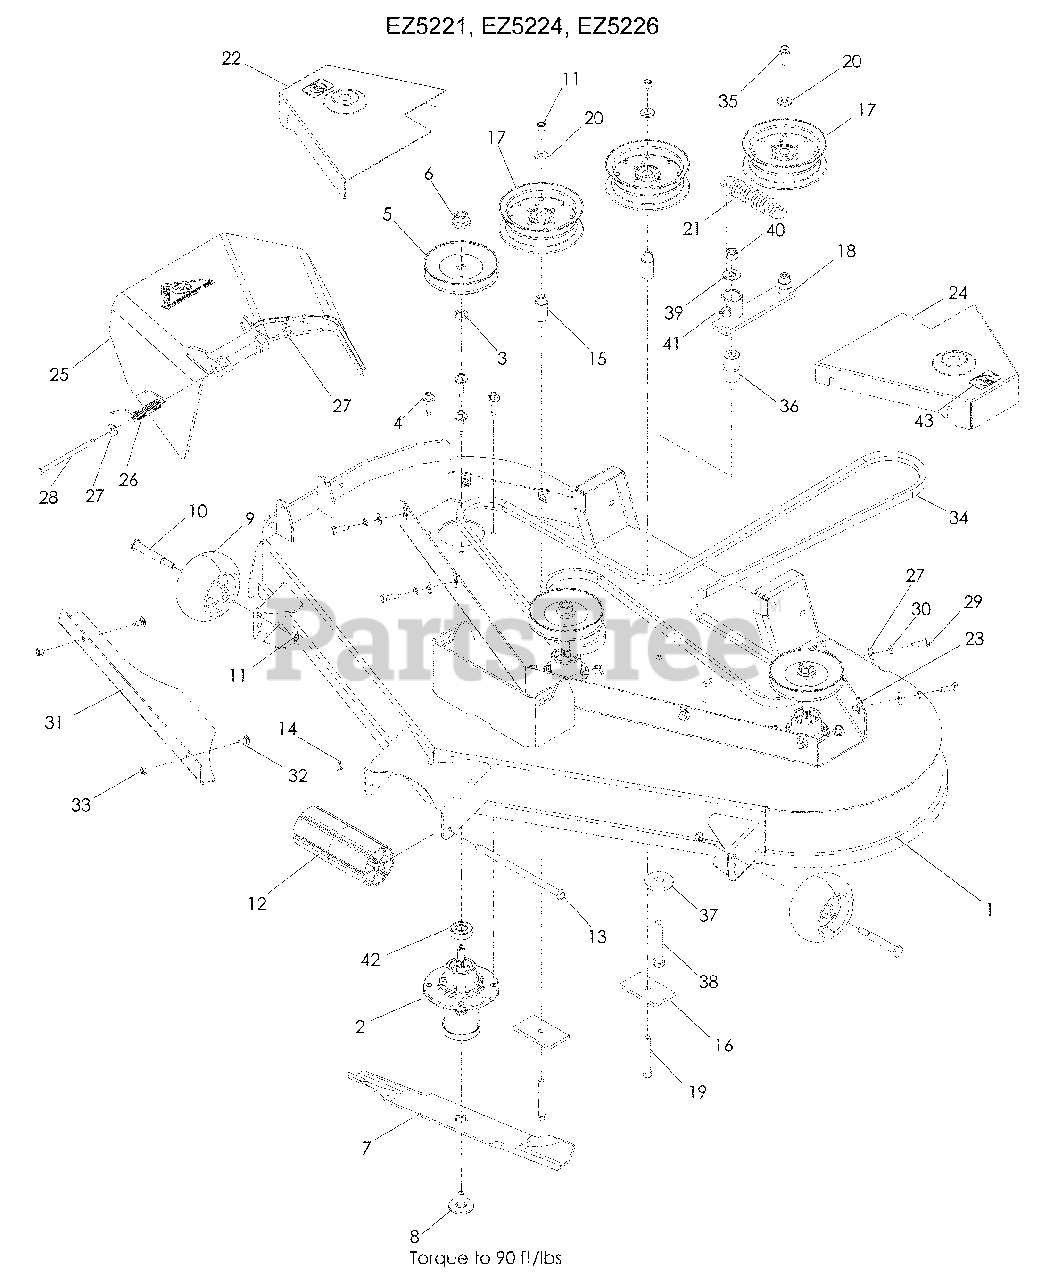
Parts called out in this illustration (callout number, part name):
1	DECK w/DECALS
2	HOUSING ASSM
3	WASHER, SPACER
4	SCREW 5/16 -18 x WSH HD
5	PULLEY
6	NUT 9/16 TOP CNTRLK
7	BLADE, 18"
8	BOLT 7/16 BLADE
9	WHEEL, GAUGE
10	BOLT ½-16 x 25/8 SHOULDER
11	NUT 3/8-16 HEX NYLOC
12	ROLLER, NOSE
13	ROD, ROLLER, NOSE
14	PIN, COTTER 1/8 x ¾
15	BUSHING, IDLER
16	PAD, PAINTED
17	PULLEY, IDLER
18	ARM, IDLER
19	HCS 3/8-16 x 3
20	WASHER 3/8 FLAT STD
22	BELT SHIELD, RT
23	RETAINER, U TYPE
24	BELT SHIELD, LT
25	CHUTE, DISCHARGE
26	SPRING, TORSION
27	WASHER 5/16 STD FLAT
28	PIN, CLEVIS 5/16
29	HCS 5/16-18 x 1
30	WASHER 5/16 SLW
31	PLATE, CONFINEMENT
32	RHSNB 5/16-18 x 5/8
33	NUT 5/16-18 HEX NYLOC
35	HCS 3/8-16 x 1 WHIZLK
36	BUSHING, PIVOT
37	WASHER, SUPPORT
38	HCS ½-13 x 3¼
39	WASHER ½ STD FLAT
40	NUT ½ HEX NYLOC
41	ZERK
42	BEARING, BALL
43	DECAL, NO STEP
